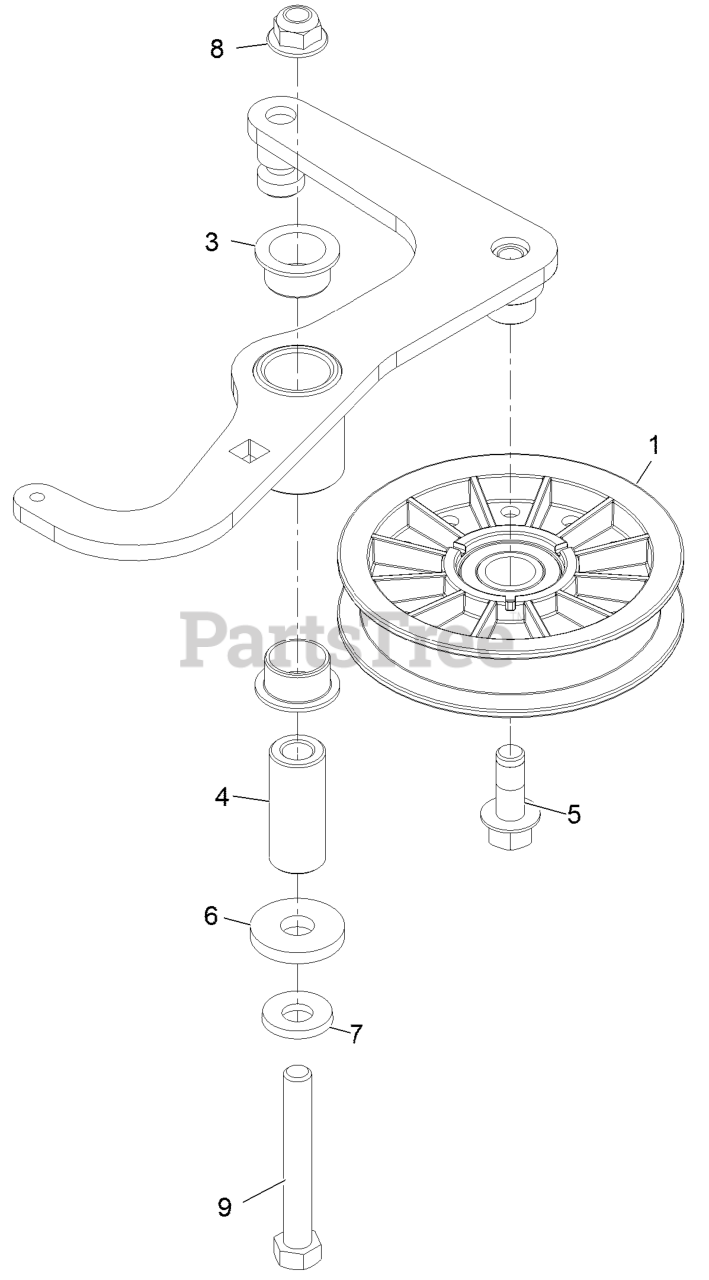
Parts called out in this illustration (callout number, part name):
1	PULLEY-IDLER, FLAT
3	BUSHING-FLANGE
4	SPACER, PIVOT
5	SCREW-HFH
7	WASHER-BELLEVILLE
8	NUT-HF, NI
9	SCREW-TAP
